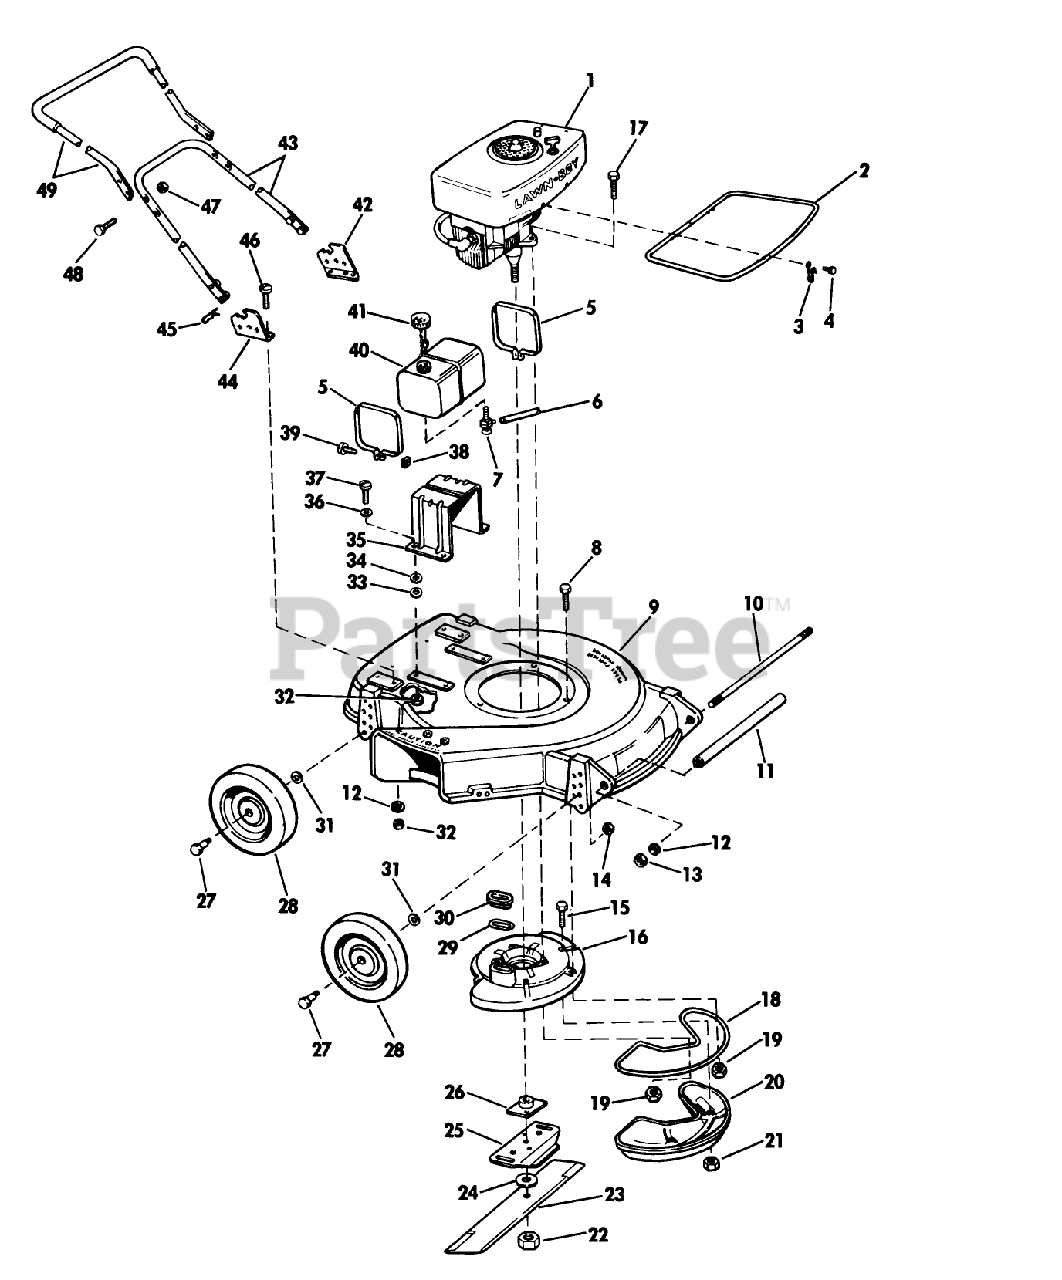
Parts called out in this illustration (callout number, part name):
7	VALVE&SCREEN SM
12	WASHER WROUGHT
13	LOCKNUT
21	LOCKNUT E
22	NUT-BLADE
26	PLATE AND COLLAR ASM
29	GASKET S
31	WASHER, LOCK
37	BOLT PIONEER
46	SCREW S
